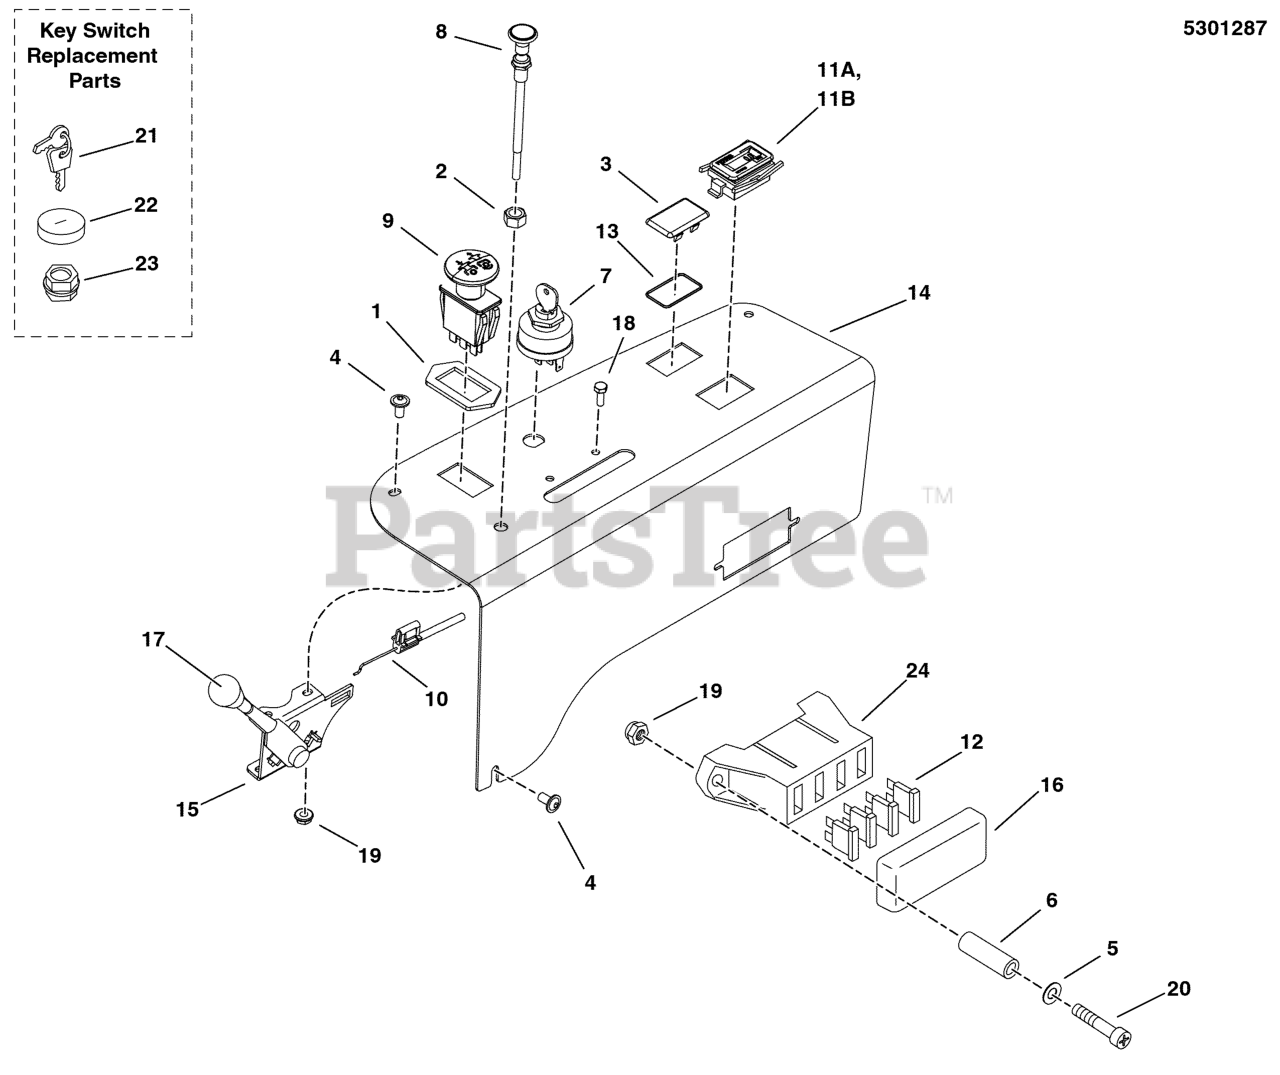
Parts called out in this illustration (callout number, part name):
1	RING, SWITCH RETAINER
2	NUT, 3/8-24 Hex Jam
3	PLUG, .820X1.44 HOLE, BLACK PLASTIC
4	SCREW, ALLEN HEAD 1/4-20X.500 ZINC PHOS
5	WASHER, #10 SAE
6	SPACER, .20 X .38 X 1.25
7	SWITCH, IGNITION, 6 POST
8	CABLE, CHOKE CONTROL, 51" (Z)
9	SWITCH, BLADE ENGAGEMENT
10	CABLE, THROTTLE 47"
11A	HOUR METER, ASSEMBLE
11B	HOUR METER
12	FUSE, ATO-20 (20 AMP)(SV)
13	O-RING, 7/8" ID X 1/16" W
14	PLATE, CONTROL PANEL - BLK
15	LEVER, THROTTLE CONTROL, HEAVY-DUTY
16	COVER, VINYL, FUSE BLOCK
17	THROTTLE CONTROL HANDLE/KNOB
18	SCREW, #10-24 X 3/4" ROUND PHILLIPS
19	NUT, Hex, Nylon Lock, #10-24
20	SCREW, #10-24 X 2" ROUND PHILLIPS
21	KEY, IGNITION MOLDED SET
22	COVER, PLASTIC, SNAP ON
23	PLASTIC NUT
24	FUSE, BLOCK (SV)
